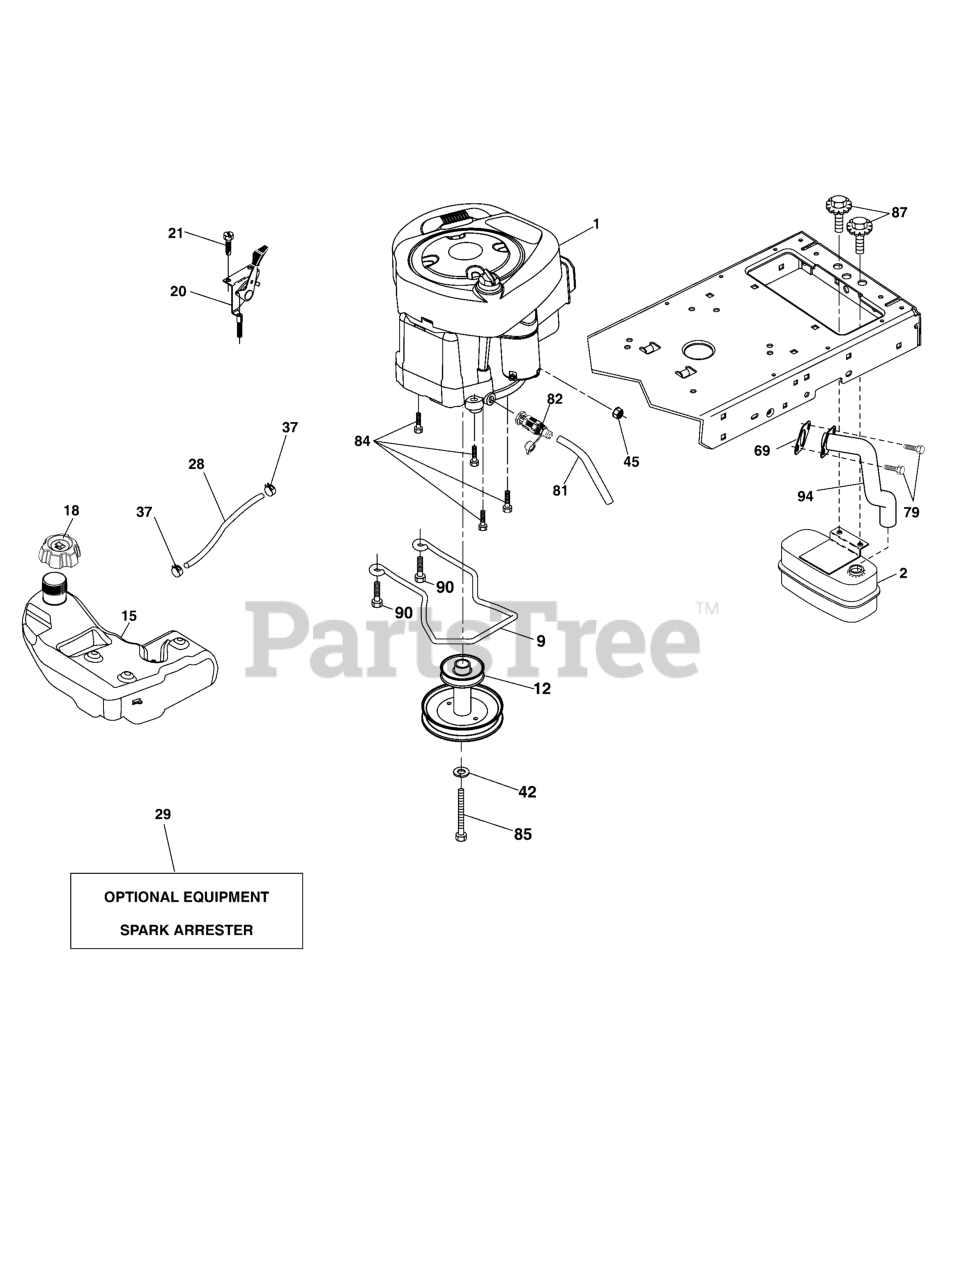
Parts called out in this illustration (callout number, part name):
1	* Engine, 20 Gross HP, B&S, Mod. 33R877-0024-G1
9	KEEPER, Engine Belt
12	PULLEY, Engine
15	TANK, Fuel
18	CAP, Fuel
20	CONTROL, Throttle/Choke
28	Fuel Line
29	Spark Arrester Kit
37	Clamp Hose
42	WASHER, 7/16 Lock SLW
69	GASKET
79	Screw Socket HD 5/16-18 x .75
81	Tube Drain Oil Easy
82	Valve Oil Drain
84	Screw 3/8-16 x 1-1/4
85	BOLT, 7/16-20 X 4 X GR. 5-1.5, Hex
87	Bolt 5/16-18 unc x 3/4 w/Sems
89	Exhaust Tube
90	Screw Hexwsh Thd 3/8-16 x 1
